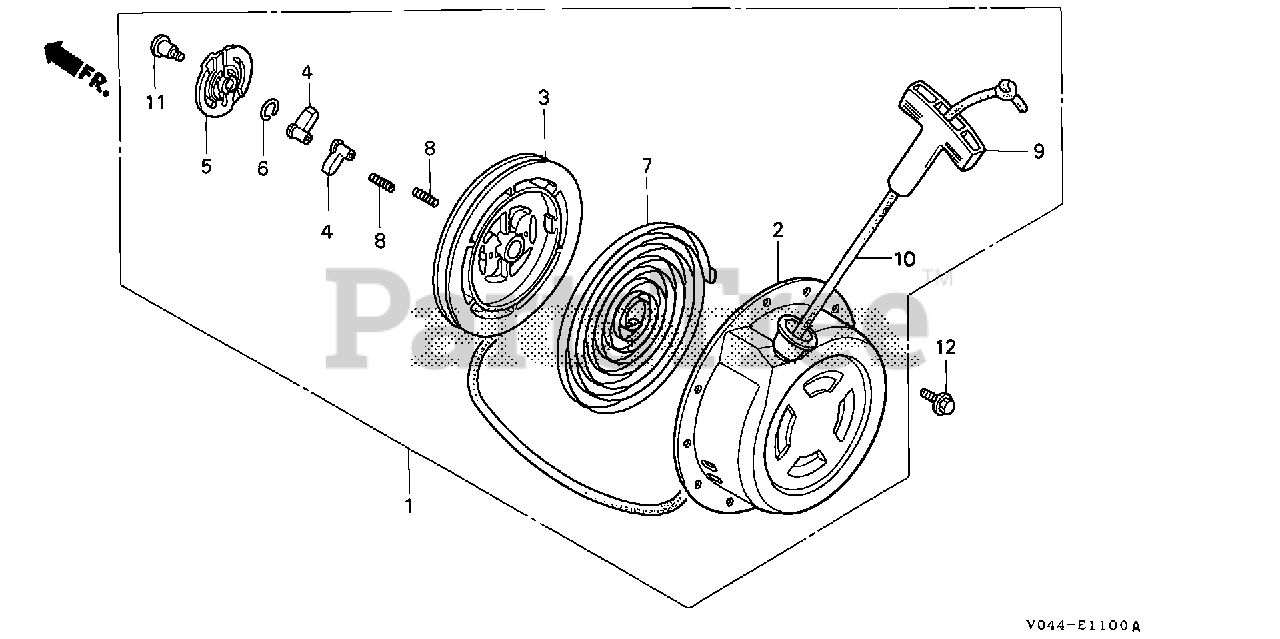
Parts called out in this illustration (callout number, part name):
1	STARTER ASSY., RECOIL *R280* (POWER RED)
2	CASE, STARTER *R280* (POWER RED)
3	REEL, RECOIL STARTER
4	RATCHET, STARTER
5	GUIDE, RATCHET
6	SPRING, FRICTION
7	SPRING, RECOIL STARTER
8	SPRING, RETURN
9	GRIP, STARTER
10	ROPE, RECOIL STARTER (NA USE ALT:08550-ZG921-11)
11	SCREW, SETTING
12	BOLT, FLANGE (6X10)
